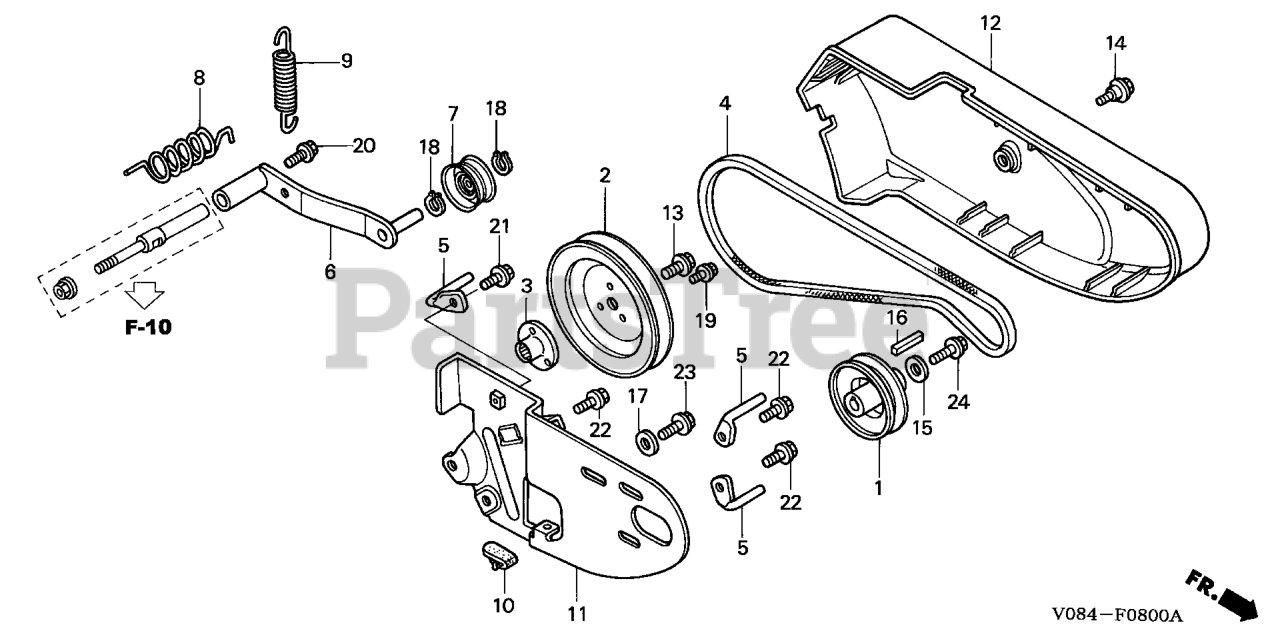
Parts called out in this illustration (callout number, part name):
1	PULLEY, DRIVE
2	PULLEY, DRIVEN (141MM)
3	BOSS, DRIVEN PULLEY
4	V-BELT (SB-38)
5	STOPPER, BELT
6	ARM, TENSION
7	ROLLER (TENSION)
8	SPRING, TENSION ARM RETURN
9	SPRING, BELT TENSIONER
10	RUBBER, STOPPER
11	COVER, BELT (INNER)
12	COVER, BELT
13	BOLT, FLANGE (8X18)
14	BOLT, FLANGE (6MM)
15	WASHER (8MM)
16	KEY (5X5X33)
17	WASHER, PLAIN (8MM)
18	CIRCLIP (OUTER) (10MM)
19	BOLT, FLANGE (6X10)
20	BOLT, FLANGE (6X16) Use from Engine SN 2056820.
21	BOLT, FLANGE (8X12)
22	BOLT, FLANGE (8X16) Use from Engine SN 1000016.
23	BOLT, FLANGE (8X20) Use up to Engine SN 1609606.
24	BOLT, FLANGE (8X25)
